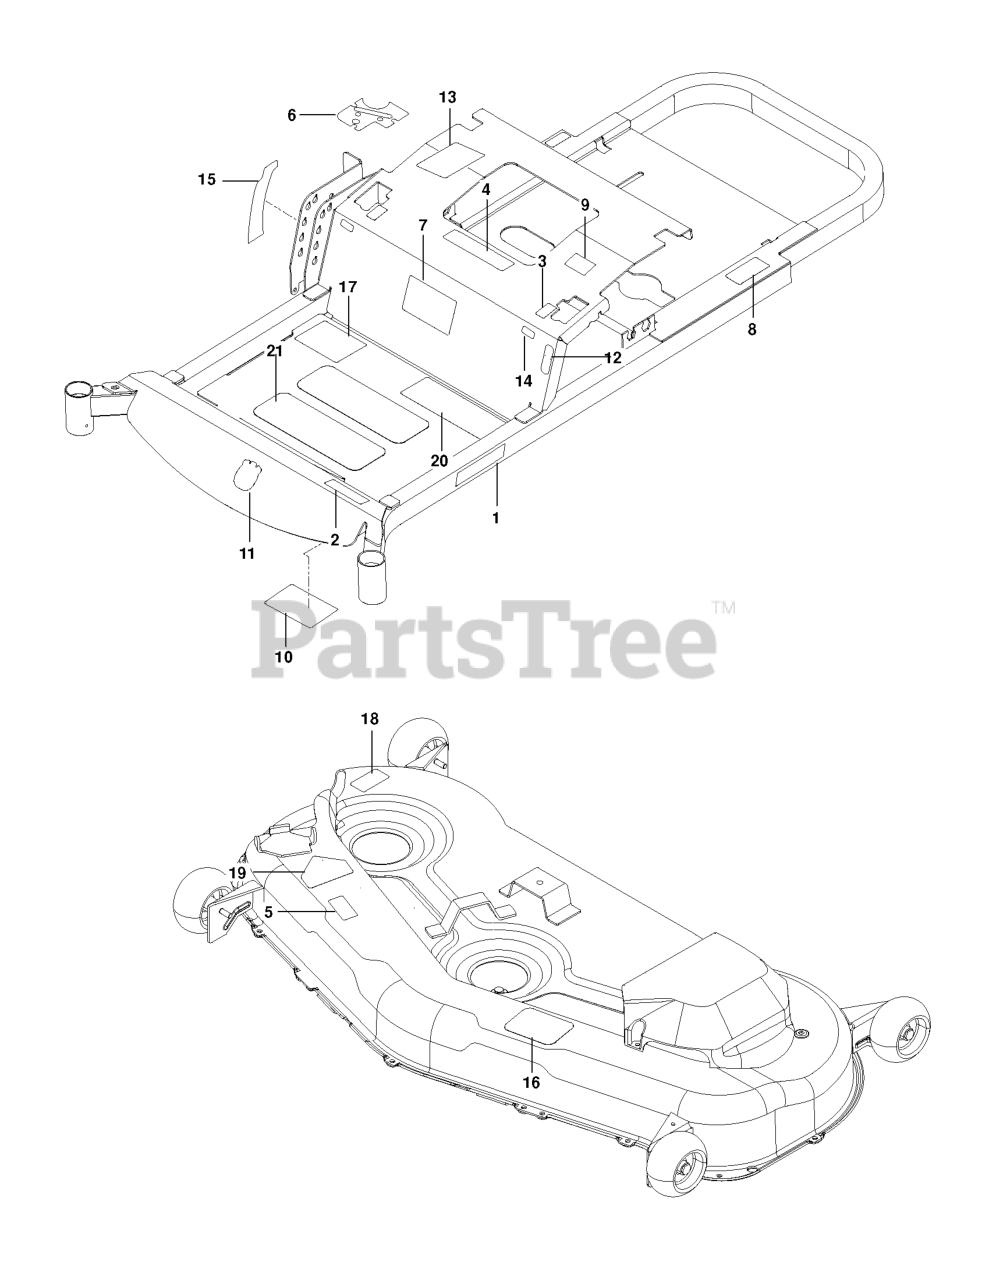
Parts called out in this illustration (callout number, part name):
1	RP.DECAL.BADGE.170MM.TEXTLOGO
2	DECAL, RZ5426
3	DECAL, MOTION CONTROL
4	EURO DECAL-BATTERY WARNIN6
5	DECAL, EURO SEVERING
6	DECAL, CTRL PANEL, HUSQ
7	DECAL, START
8	DECAL, DO NOT TOW
9	DECAL, EXITING MOWER
10	DECAL, SERVICE
11	DECAL.AUGER.HUSQ.CROWN.SNOW
12	DECAL, PARK BRAKE
13	DECAL, CUSTOMER RESPNSIBILITY
14	DECAL, F.S.T.
15	DECAL, DECK HEIGHT, HUSQ
16	DECAL, BELT ROUTING
17	DECAL, WARNING
18	DECAL.DECK.6MIL./DEF.SHLD.WARN
19	DECAL, CPSC
20	DECAL, SAFETY WARNING
21	ANTI-SKID PAD
